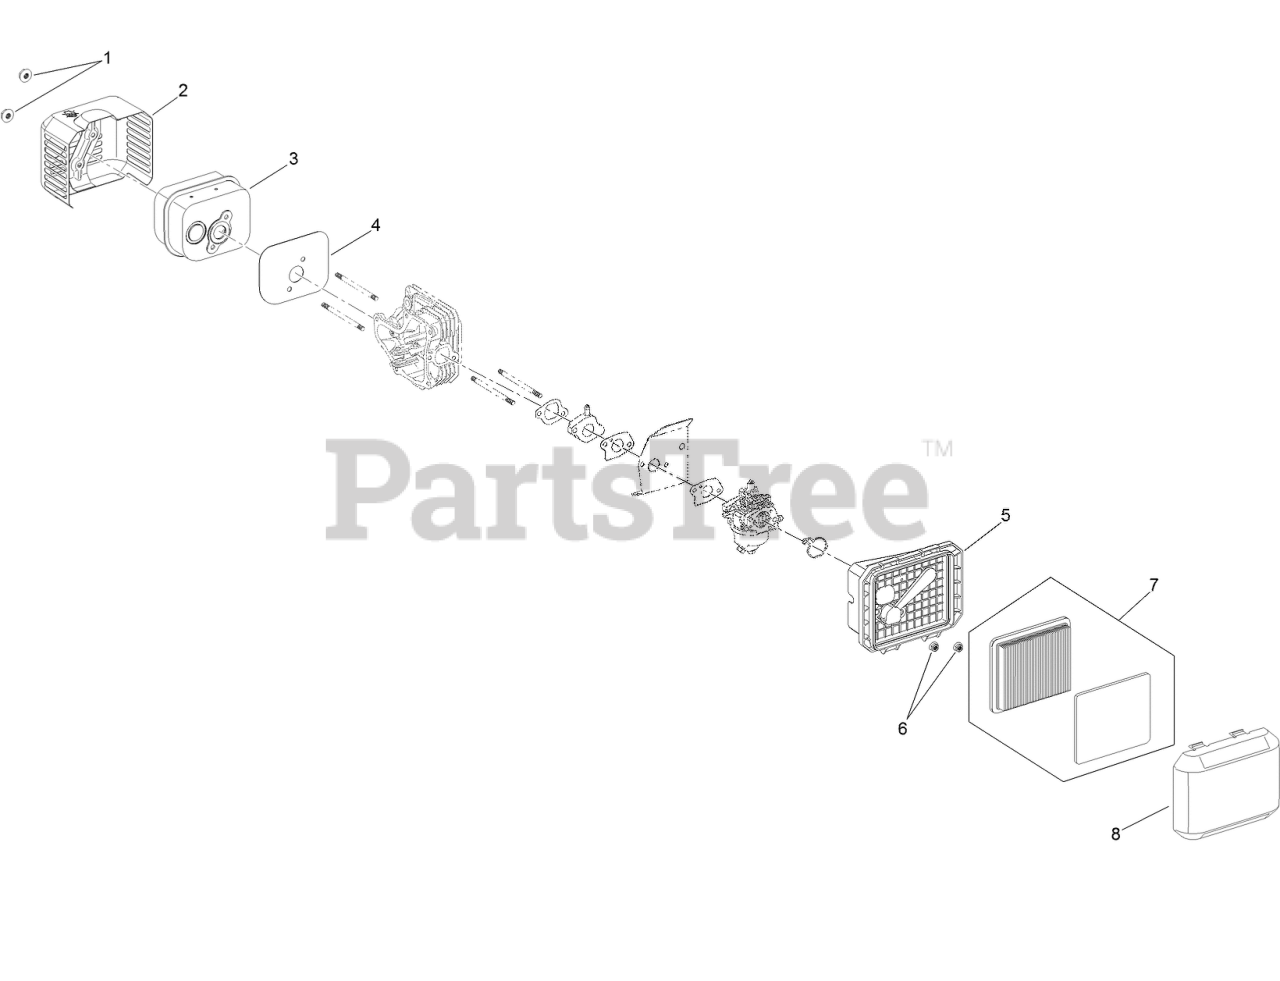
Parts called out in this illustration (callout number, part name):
1	NUT-FLANGE
2	SHIELD-MUFFLER
3	MUFFLER ASM
4	GASKET-EXHAUST
5	BASE-CLEANER, AIR
6	NUT-FLANGE
7	AIR FILTER AND PREFILTER KIT
8	COVER-CLEANER, AIR
